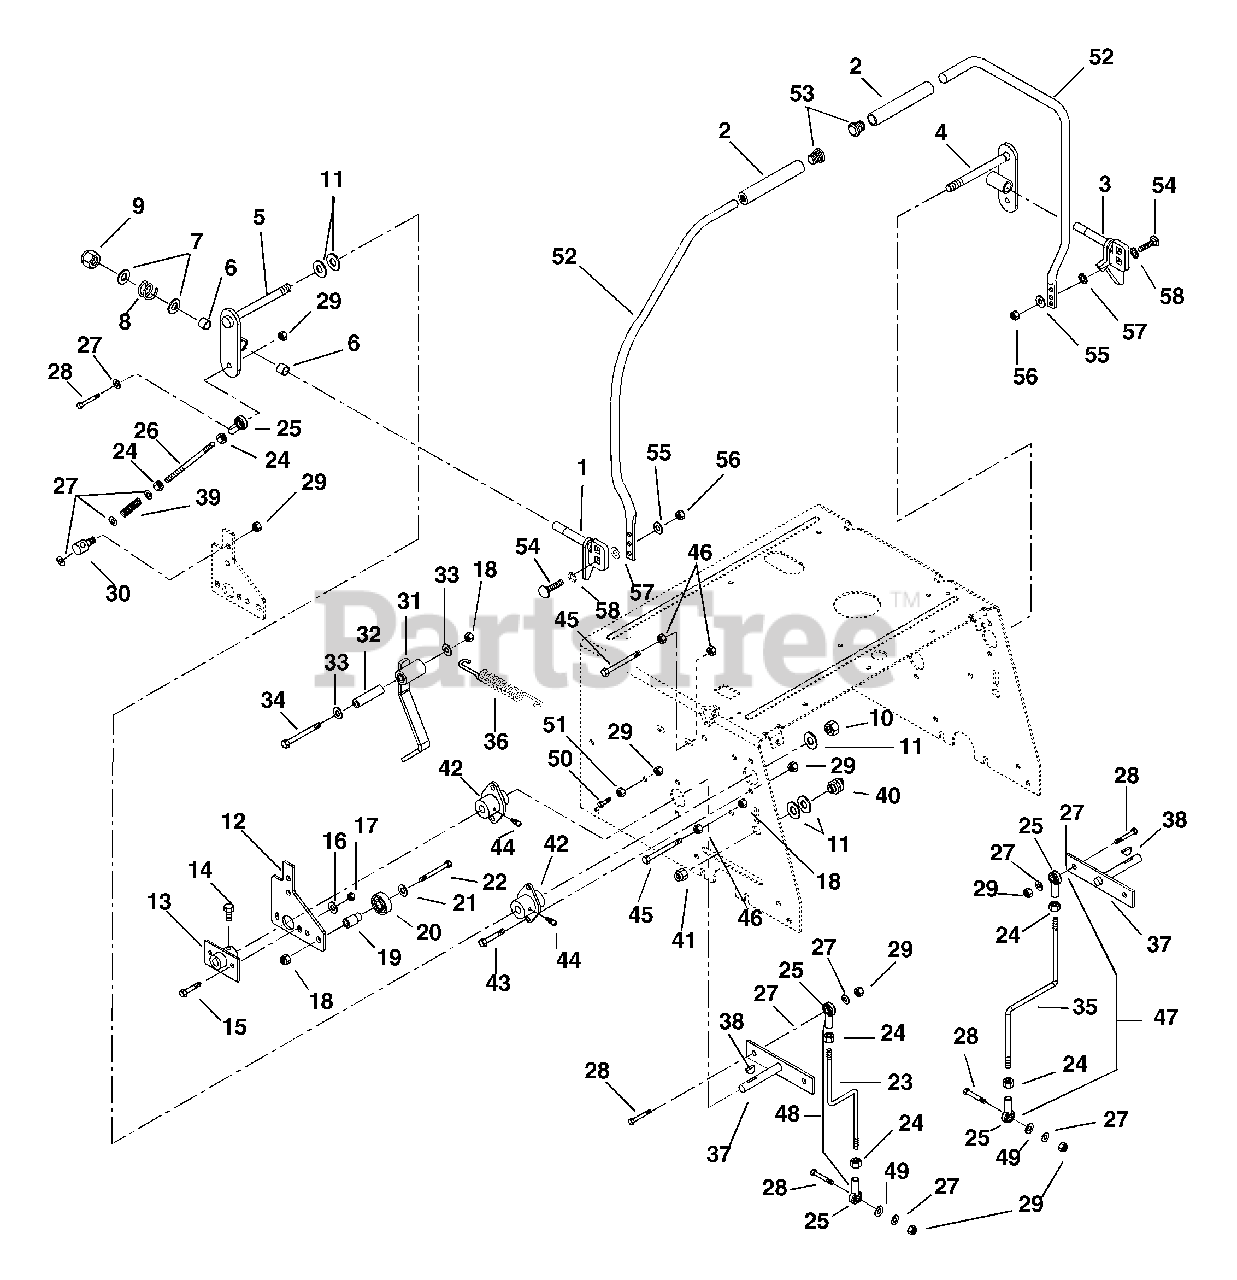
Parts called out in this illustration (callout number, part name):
1	Weldment-Lever Right Hand
2	Grip-Handlebar
3	Weldment-Lever Left Hand
4	Weldment-Rod Left Hand
5	Weldment-Tube Right Hand
6	Bushing-Nylon .5 x .625 x .5
7	Washer-Plastic .12 x .53 x 1.12
8	Spring-Compression
9	Nut-Locking Cone .500-1
10	Nut-Locking .50-20
11	Washer-Flat, Steel .563 x 1.375 x .109
12	Arm-Speed Control
13	Arm-Speed Control
14	Bolt-Hex .25-20 x .50 Grade 5
15	Bolt-Hex .25-20 x .75 Grade 5
16	Washer-Flat Steel .281 x .620 x .065
17	Nut-Locking .250-20
18	Nut-Locking .375-16
19	Hub-Bearing Mount
20	Bearing-Ball .500 x 1.375 x .437
21	Washer-Flat, Steel .406 x .812 x .065
22	Bolt-Hex .38-16 x 2.00 Grade 5
23	Rod-Transaxle Right Hand
24	Nut-Jam .31-24
25	Rod-End-Female .312
27	Washer-Flat-Steel .344 x .688 x .065
28	Bolt-Hex .31-18 x 1.00 Grade 5
29	Nut-Locking-Center .312-18
30	Rod-Pivot
31	Weldment-Neutral Detent
32	Bushing-Sleeve .385 x .610 x 1.80
33	Washer-Flat-Steel .406 x .812 x .065
34	Bolt-Hex .38-16 x 2.75 Grade 5
35	Rod-Transaxle Left Hand
36	Spring, Tension .085 x .60 x 5.13
37	Weldment-Pump
38	Key-Woodruff .13 x .75
40	Switch-Neutral
41	Nut-Stamped .56-18
42	Bushing-Flanged
43	Bolt-Hex .31-18 x .75 Grade 5
44	Fitting-Lube .25-28 x .256
45	Bolt-Hex .38-16 x 3.00
46	Nut-Hex .375-16 Grade 2
47	Rod Assembly-Transaxle Right Hand
48	Rod Assembly-Transaxle Left Hand
49	Washer-Flat-Steel .344 x 1.375 x .075
50	Bolt-Hex .31-18 x .75
51	Nut-Hex .31-18
52	Handlebar-Large Frame
53	End Cap-Steering Lever Tube
54	Bolt-Round Head Square Neck .31-18 x 1.00 Grade 5
55	Washer-Flat-Steel .38 x .875 x .083
56	Nut-Locking-Flange .31-18
57	Washer-Locking-External .326 x .599 x .031
58	Washer-Locking-Internal .438
